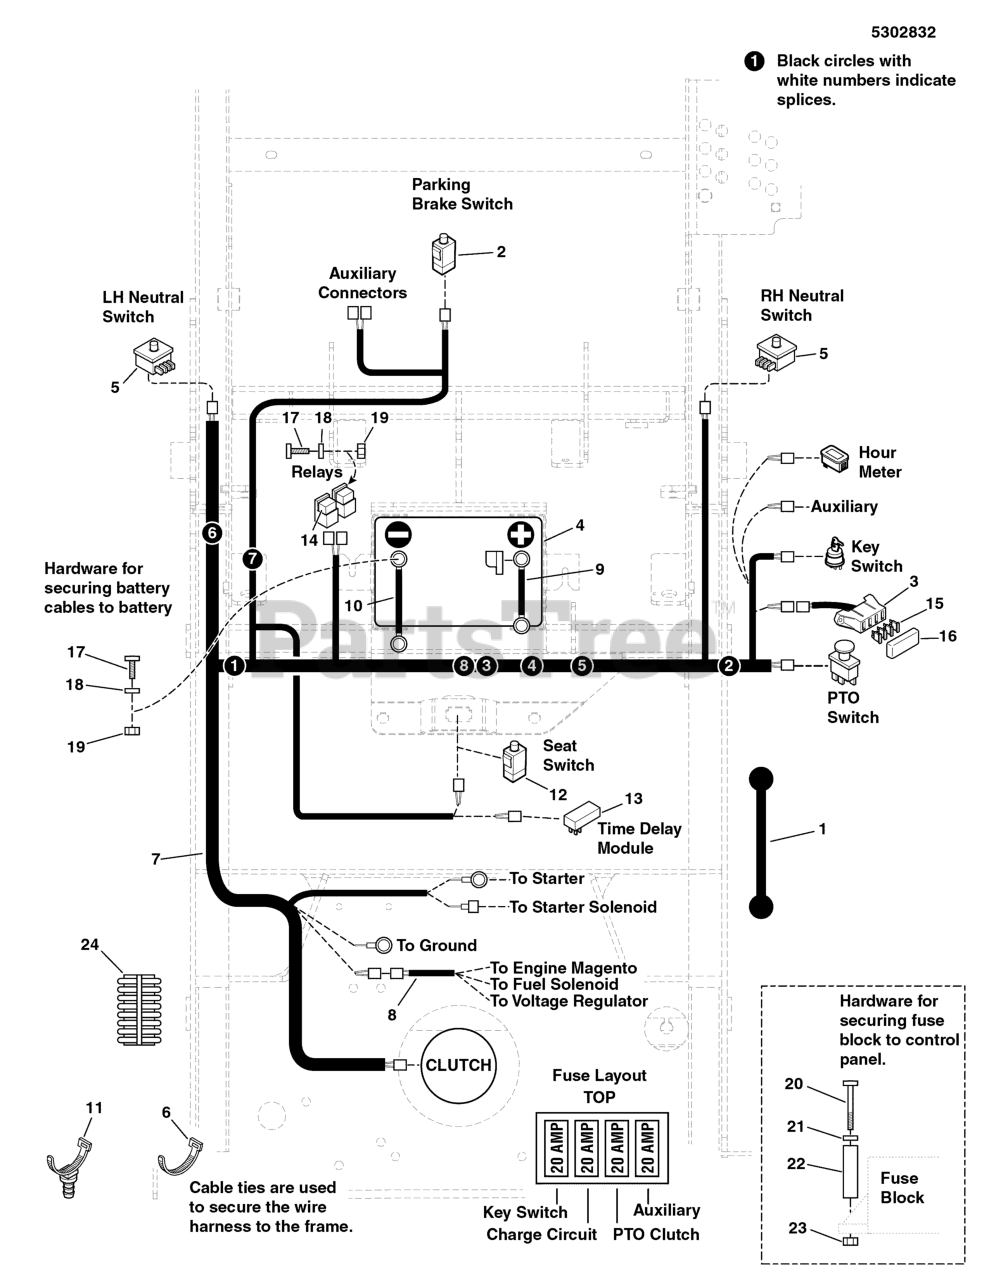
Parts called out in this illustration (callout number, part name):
1	STRAP-BLACK RUBB
2	SWITCH, DP NO/NC SNAP-IN
3	WIRE HARNESS, FUSE BLOCK - IS2000
5	SWITCH, LOW PROF, NC/NO
6	CABLE TIE, 12
7	WIRE HARNESS, MAIN, S150XT
8	WIRE HARNESS, BIG BLOCK KAWI JUMPER
9	BATTERY CABLE, POSITIVE, 35
10	BATTERY CABLE, NEGATIVE, 35
11	CABLE TIE FIR TREE MOUNT, WAYTEK 21374
12	SWITCH, PLUNGER, NO/NO SNAP-IN
13	MODULE, TIME DELAY
14	RELAY, 12V, 40A
15	FUSE, 20 AMP, ATO
16	COVER, VINYL FUSE BLOCK
17	BOLT, 1/4-20 X 3/4 GD5 YZ
18	WASHER, 1/4 SAE
19	NUT, 1/4-20 HEX SERR. FLANGE
20	SCREW, #10-24 X 2 ROUND PHILLIPS
21	NUT, #10-24 HEX NYLON LOCK
22	WASHER, #10 SAE
23	SPACER, .20 X .38 X 1.25
24	WIRE LOOM, 3/8 ID X 15 IN
